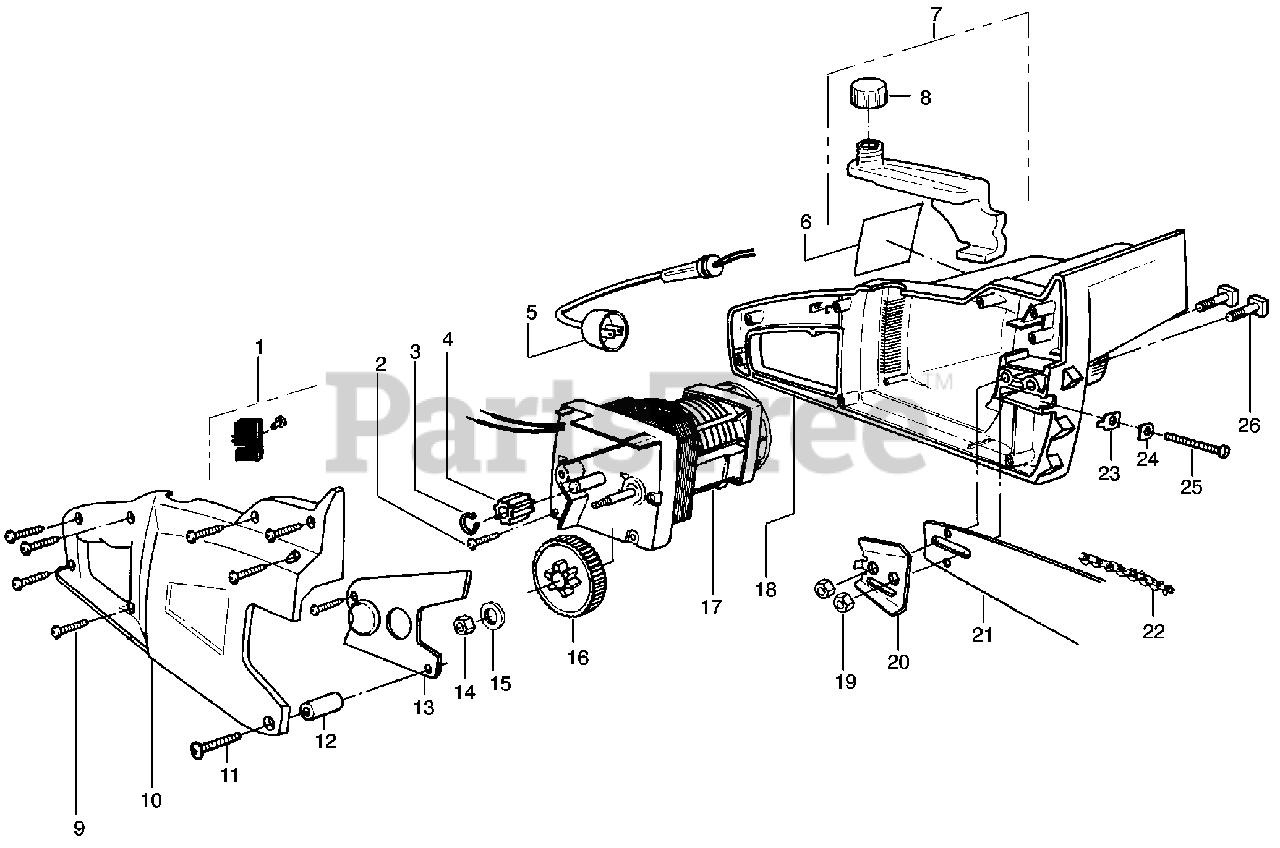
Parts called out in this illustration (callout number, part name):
2	Screw
3	Retaining Ring
4	Pinion Gear
6	Warning Decal (PLN-CAN.-1420)
6	Warning Decal (PLN-1420)
7	Oil Tank Assembly
9	Screw
10	Hsg - Right
13	Gear Cover
16	Gear Assy
17	Motor Ass'y.
18	Motor Hsg - Left
22	14" -Chain
24	Bar Adjusting Plate
26	Bar Mounting Bolt
